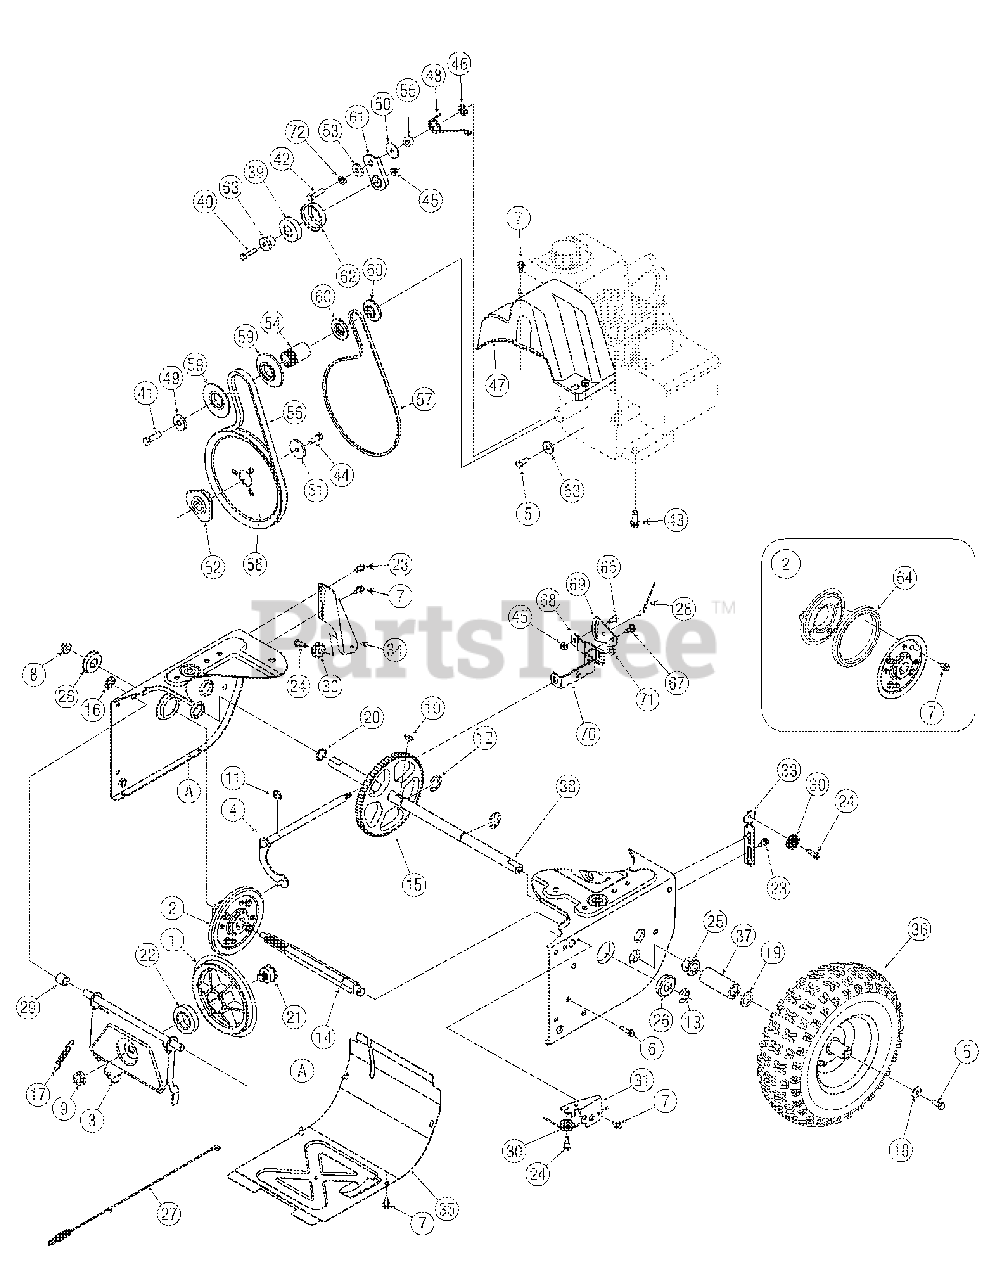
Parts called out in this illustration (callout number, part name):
1	Disc, Friction Wheel
2	Friction Wheel Assembly, 5.5 OD
4	Shift Assembly, Rod
5	Hex Screw, 5/16-24, .750, Gr5
6	Screw, 1/4-20, 1.000
7	Screw, 1/4-14 x .625
8	Nut, Flange Lock, 3/8-16, Nylon
9	Nut, Jam Lock, 5/8-18, Gr5,
10	Key, Hi Pro, 3/16 x 3/4
11	E-ring, .500 Dia.
12	E-ring, Retaining, .875 Dia.
13	E-ring, .750 Dia.
14	Hex Shaft, .8125, 7-Tooth
15	Gear, 80-Tooth
16	Speed Nut, .500
17	Extension Spring
18	Washer, Bell, .340 x .872 x .060
19	Washer, Flat, .793 x 1.24 x .060
20	Washer, Flat, .75 x 1.00 x .060
21	Pin, Friction Disc
22	Ball Bearing, 30 x 55 x133
23	Screw, Shoulder, .37 x .105, 1/4-20
24	Screw, 1/4-28, .375
25	Bearing, Hex Flange x .75 ID
26	Bearing, Ball, 17 x 40 x 12
27	Clutch Cable, Wheel, 44.95"
28	Clutch Cable, Auger, 47.23"
29	Spacer, .508 ID x .75 OD
30	Roller, Cable
36	Valve Only
37	Spacer, 1.25 x .75 x 3.0
38	Axle, .75 x 22"
39	Ball Bearing
40	Hex Screw, 1/4-20, 1.25, Gr5
41	Hex Screw, 3/8-24, 1.25, Gr8
42	Hex Screw, 5/16-24, 1.25, Gr5
43	Screw, Sems, 3/8-16, 1.00
44	Hex Screw, 5/16-24, .875, Gr8
45	Nut, Flange Lock, 1/4-20, Nylon
46	Nut, Push-on, .25 Dia.
47	Cover, Belt
48	Spring, Torsion, .850 ID x ..354
49	Washer, Flat, .406 x 1.25 x .157
50	Washer, Flat, .330 x 1.25 x .06
51	Washer, Flat, .34 x 1.50 x .150
52	Pulley, Adap, .75 Dia W/dd
53	Spacer, Shoulder
54	Spacer, .875 ID x 1.185 OD
55	Spacer, .340 x .750 x .360
56	Belt, Auger Drive
57	Belt, Wheel Drive
58	Pulley, Auger Drive, 8.1 x .5
59	Pulley, Half, V x 2.600 OD
60	Pulley, Half, 1/4-V x 1.5 OD
61	Idler Bracket, Wheel Drive
62	Sleeve, Bearing Idler
63	Spacer, Shoulder, .26 x .79 x .538
64	Rubber, Friction Wheel, 5.5 OD
65	Hex Screw, 1/4-20, .620, Gr5
66	Spring, Torsion, .750 ID x .968
67	Screw, Shoulder, .37 x .105, 1/4-20
68	Bracket, Shift Spacer
71	Nut, Flange Lock, 5/16-18, Nylon
72	Washer, Lock, 5/16
